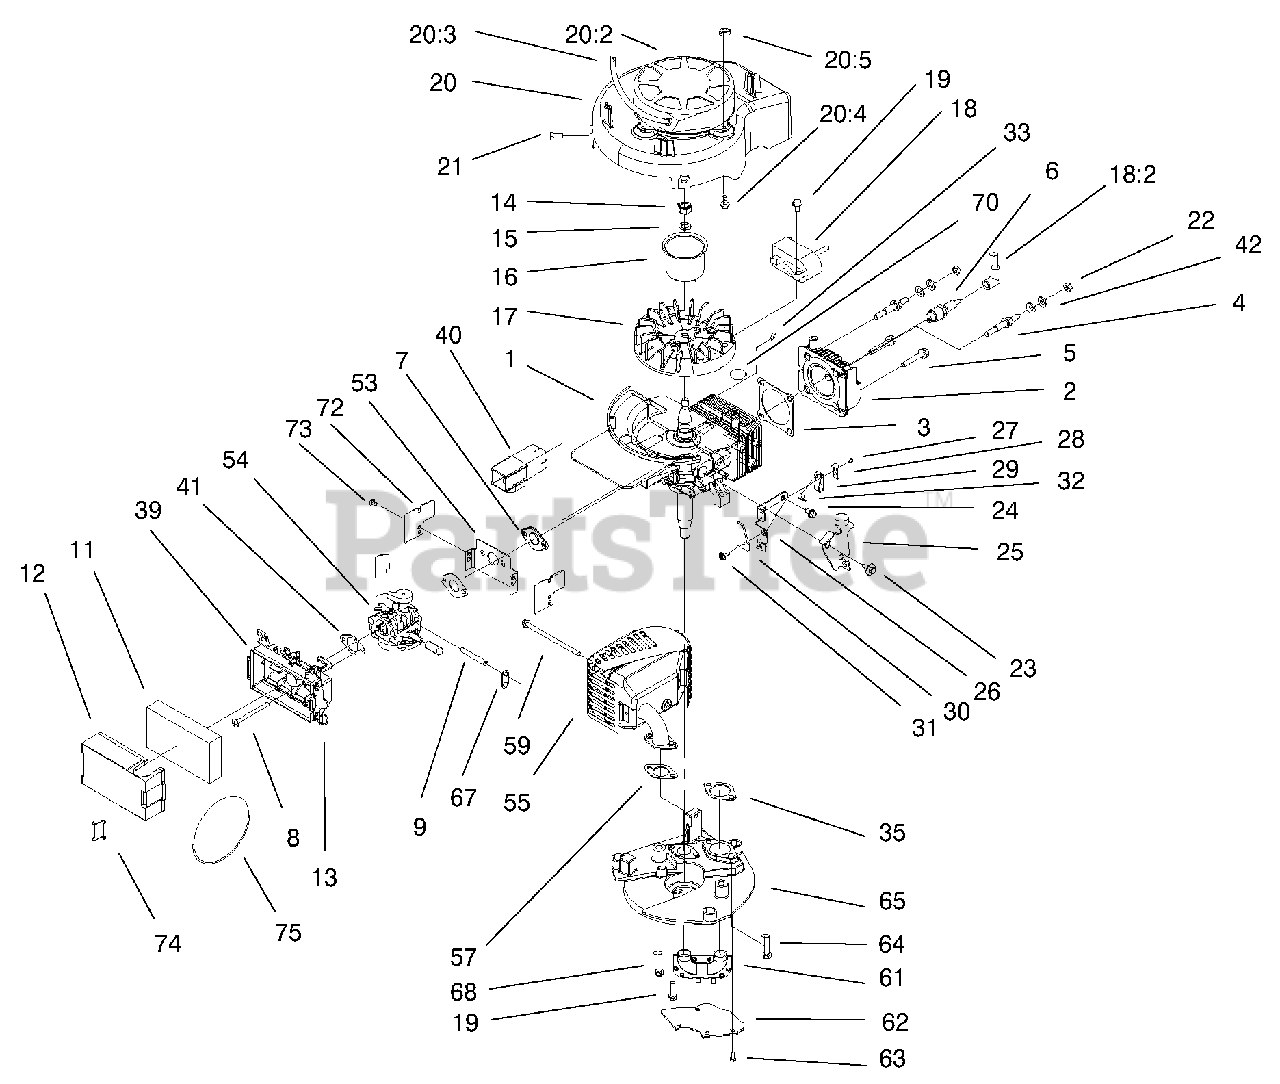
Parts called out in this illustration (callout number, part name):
1	Short Block ASM
2	Head-Cylinder
3	Gasket-Head
5	Bolt-Head
6	Plug-Spark
7	Gasket-Intake
9	Hose-Primer
11	Filter-Air
12	Cover Air Filter Modified
13	Retainer Cover
15	Washer-Lock
16	Cup-Starter
17	Flywheel
18	Module-Ignition
18:2	Lead-High Tension
20	Shroud-Recoil
20:2	Recoil ASM
20:4	Screw-HWH
20:5	Nut-Lock
21	Screw-HH
23	Screw-Shoulder
24	Screw-HWH
25	Brake Plate ASM
26	Plate-Brake
27	Rivet-Plastic
28	Strap-Insulation
29	Strap-Ground
30	Stop-Ground Strap
32	Lead Wire-Brake Switch
35	Gasket-Exhaust
39	Air Base ASM
40	Tunnel-Inlet
41	Gasket-Filter
42	Washer-Belleville
53	Shield-Carburetor
54	Carburetor ASM
55	Muffler And Guard ASM
59	Bolt-Console
61	Pipe-Transfer
62	Cover-Muffler
63	Screw-HH
64	Screw-HH
65	Plate-Muffler
67	Hose-Retainer
68	Screw-HH
70	Strap-Tie
72	Shield-Governor
74	Hook Cover
75	O-Ring-Cover
